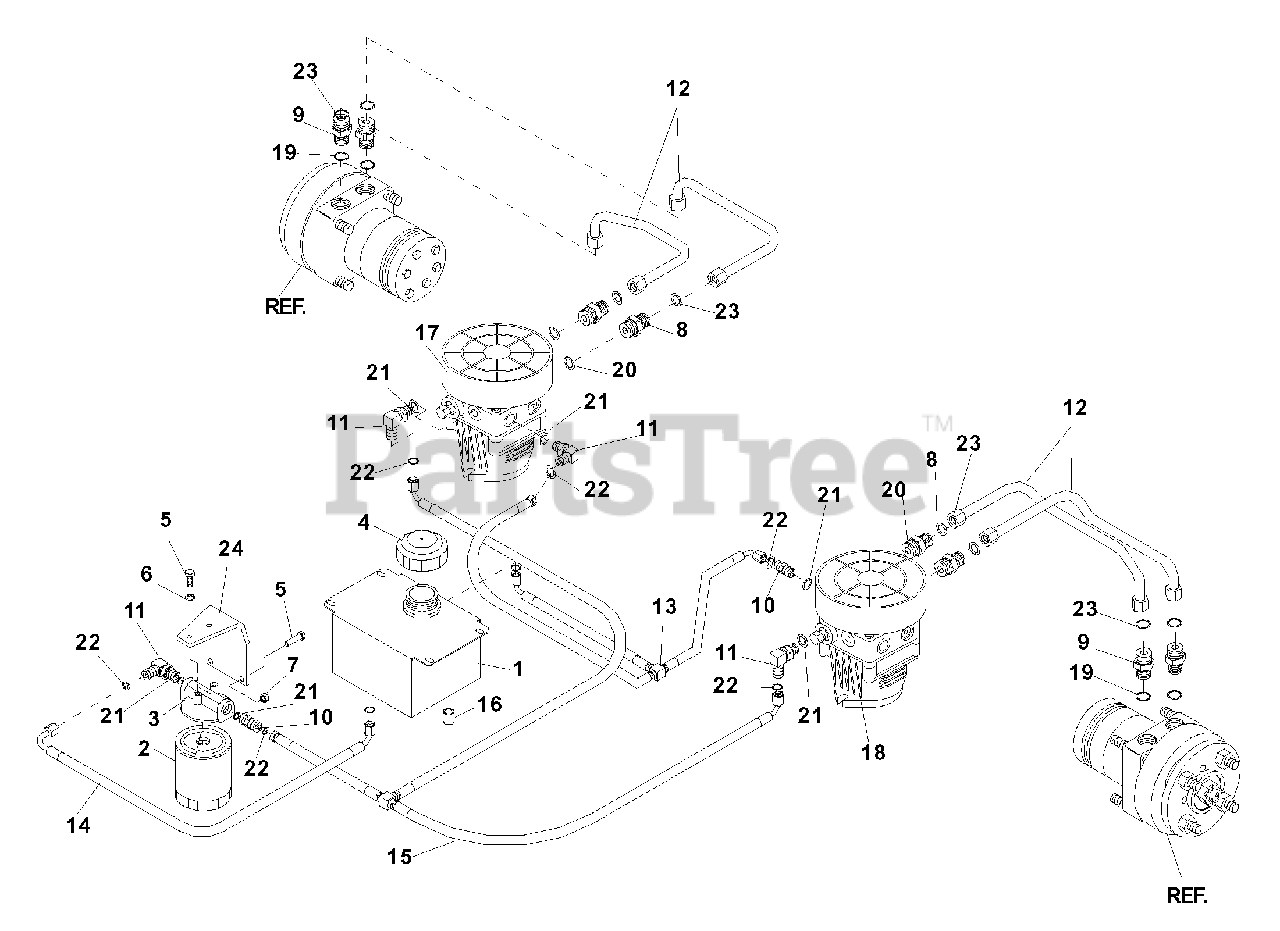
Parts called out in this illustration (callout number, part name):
3	FILTER HEAD
4	HYDRAULIC CAP
5	HCS, 1/4C x 3/4
6	LOCKWASHER, 1/4
7	NUT, 1/4C, NYLOC
9	STRAIGHT FITTING
12	HYDRAULIC LINE
13	'T' ASSEMBLY, RETURN
15	'T' ASSEMBLY
17	PUMP W/FANS, 10CC, RIGHT
18	PUMP W/FANS, 10CC, LEFT
20	O-Ring, SAE J126 Port
21	O-Ring, SAE J126 Port
24	BRACKET, FILTER
